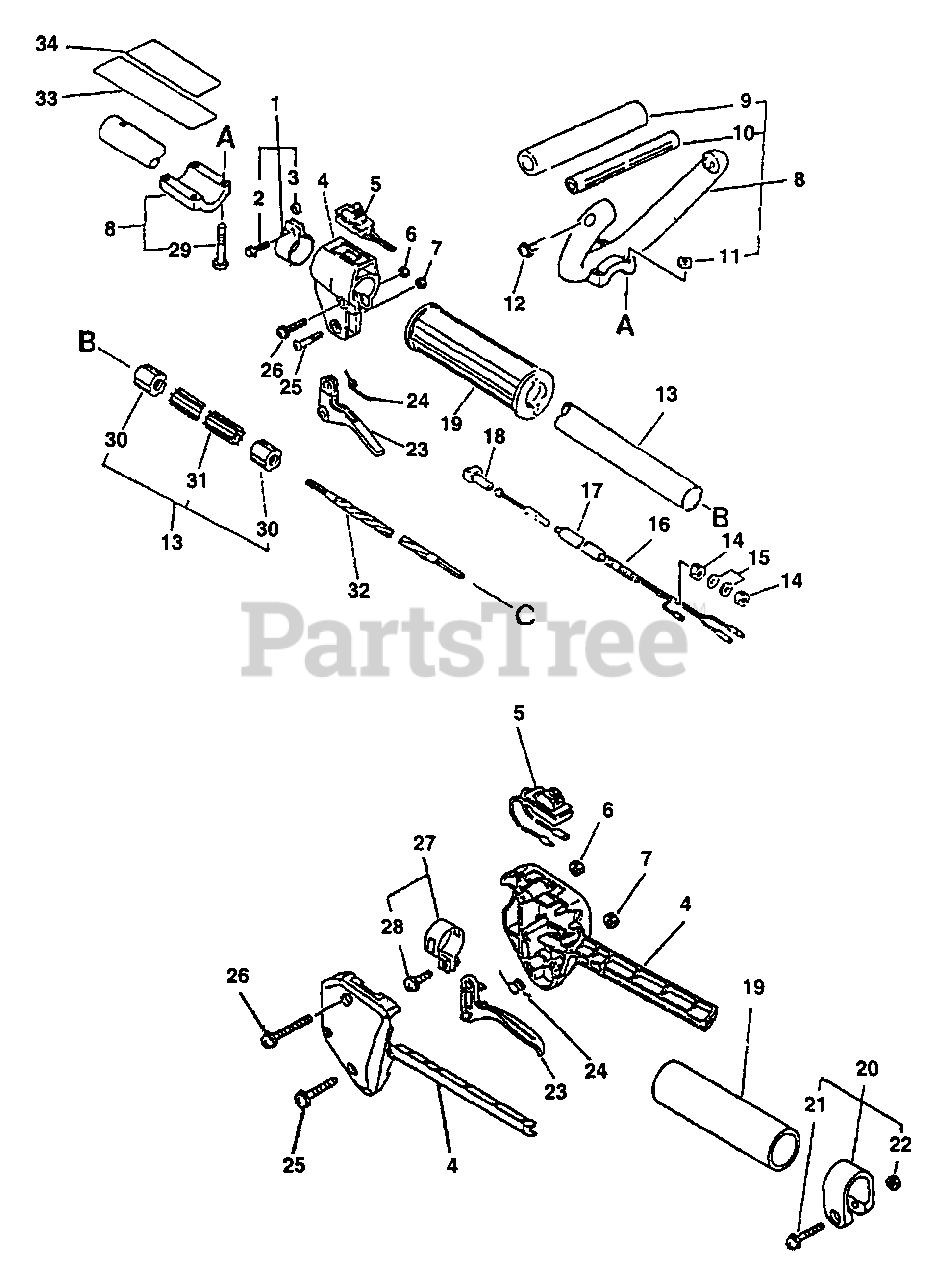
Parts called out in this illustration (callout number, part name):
1	CLAMP
2	BOLT - 5X18
4	BRACKET, THROTTLE CONTROL
4	CONTROL HANDLE KIT
5	IGNITION SWITCH ASSY
7	LOCKNUT - 5
8	LOOP HANDLE ASSY
9	GRIP, HANDLE
12	SCREW - 5X30
13	MAIN PIPE ASSY
15	WASHER - 6
16	CABLE, THROTTLE
17	TUBE - VINYL
18	GUIDE, CABLE
19	GRIP, HANDLE
20	CLAMP KIT
21	SCREW - 5X28
22	NUT - 5
23	TRIGGER, THROTTLE
24	SPRING, TRIGGER
25	SCREW - 5X30
25	SCREW - 5X25
26	SCREW - 5X30
26	SCREW - 5X35
27	CLAMP KIT
28	SCREW - 5X14
29	SCREW - 5X35
31	LINER - FLEXIBLE
32	DRIVESHAFT - FLEXIBLE
33	LABEL - CAUTION
34	LABEL - CAUTION
